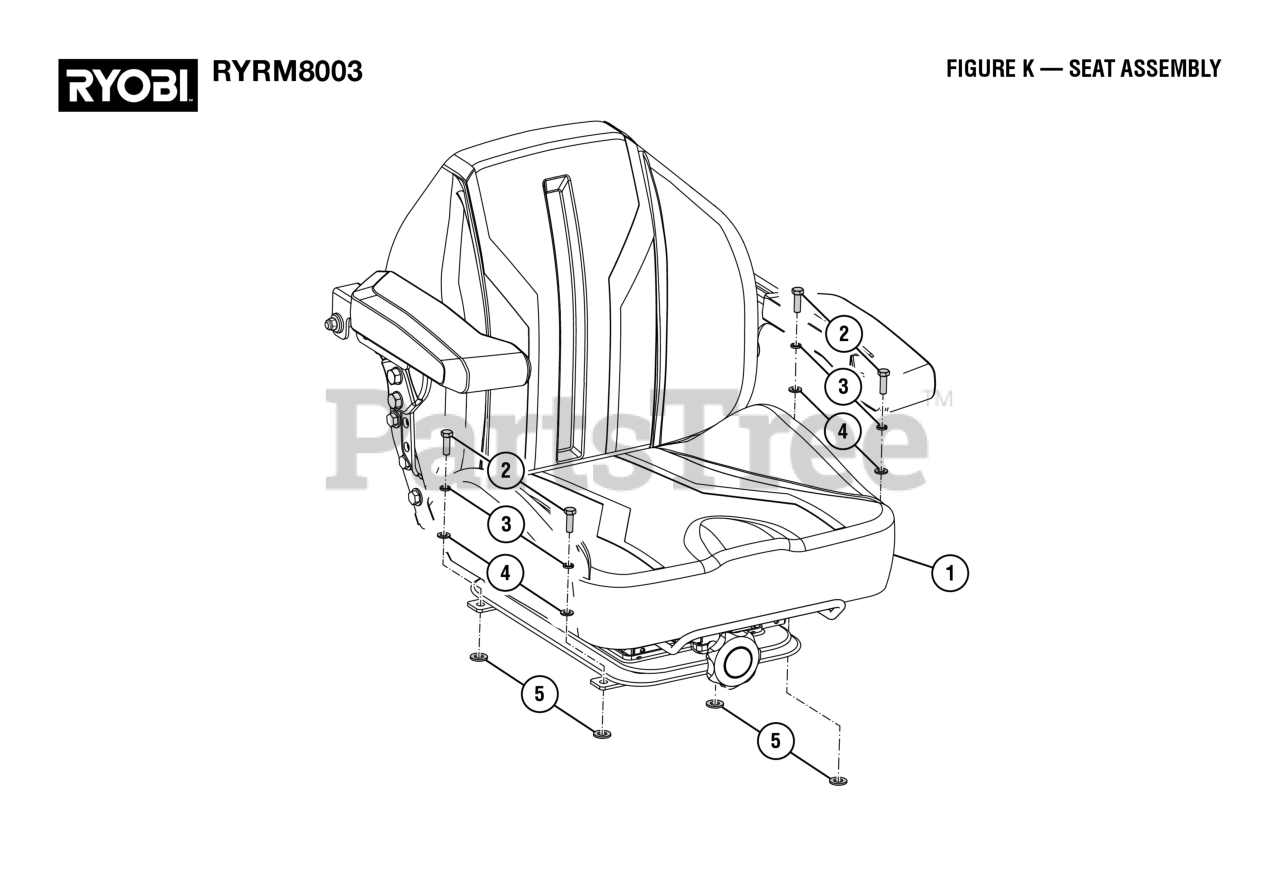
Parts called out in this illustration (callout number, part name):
2	Bolt (M8 x 25 mm, Hex Hd.)
3	Lock Washer (OD9.8 x ID8.5 x 5t)
4	Washer (OD16 x ID8.4 x 1.6t)
5	Washer (OD24 x ID13 x 2.5t)
